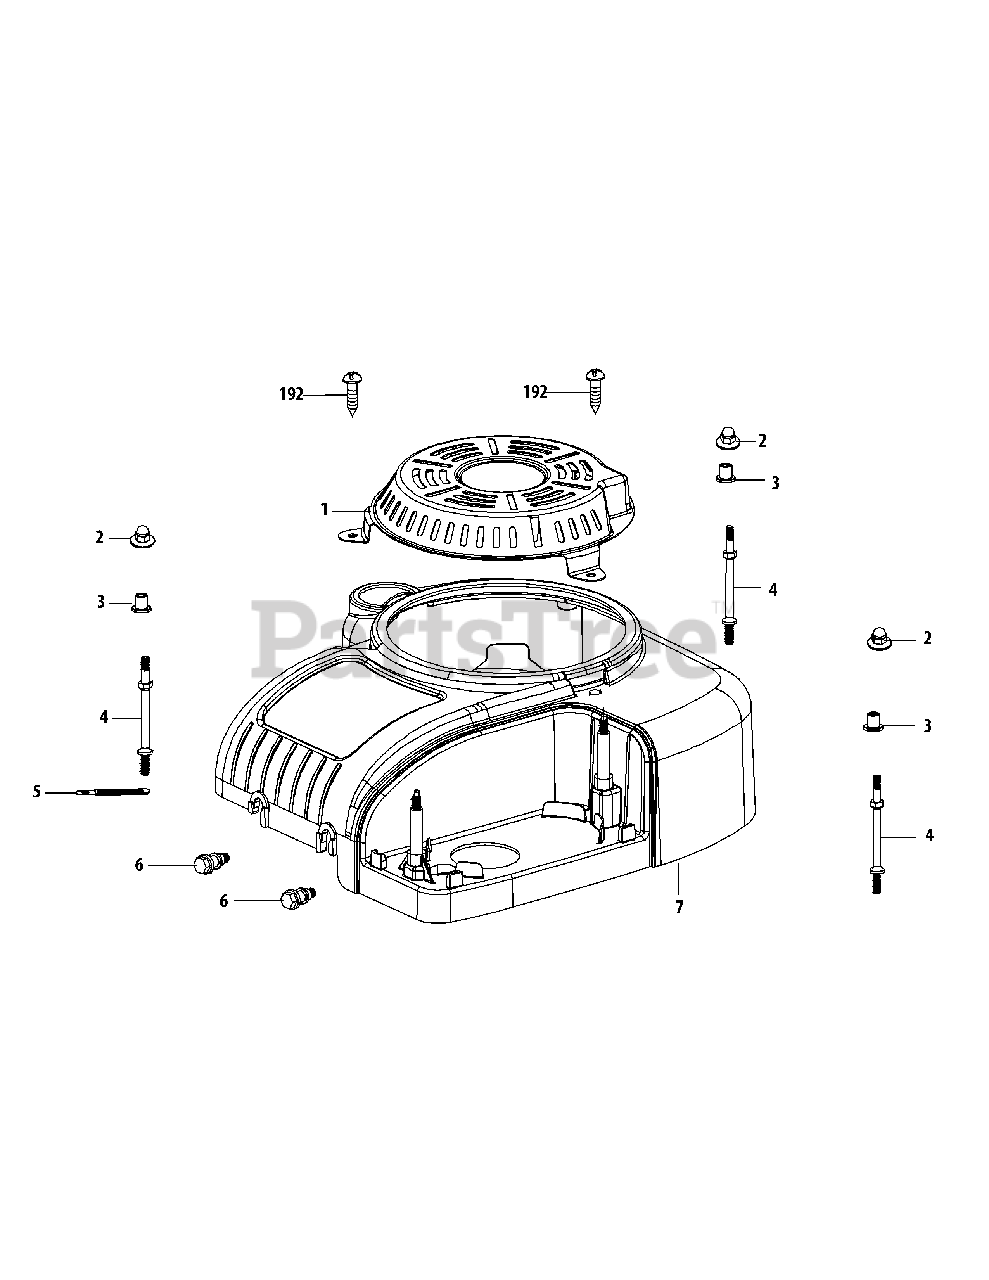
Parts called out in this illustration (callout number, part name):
1	Debris Shield
3	Engine Shroud Spacer
4	Starter / Shroud Stud M6×100
5	Flexible Clamp
7	Air Shield
192	Self-Tapping Bolt 5.5×25
